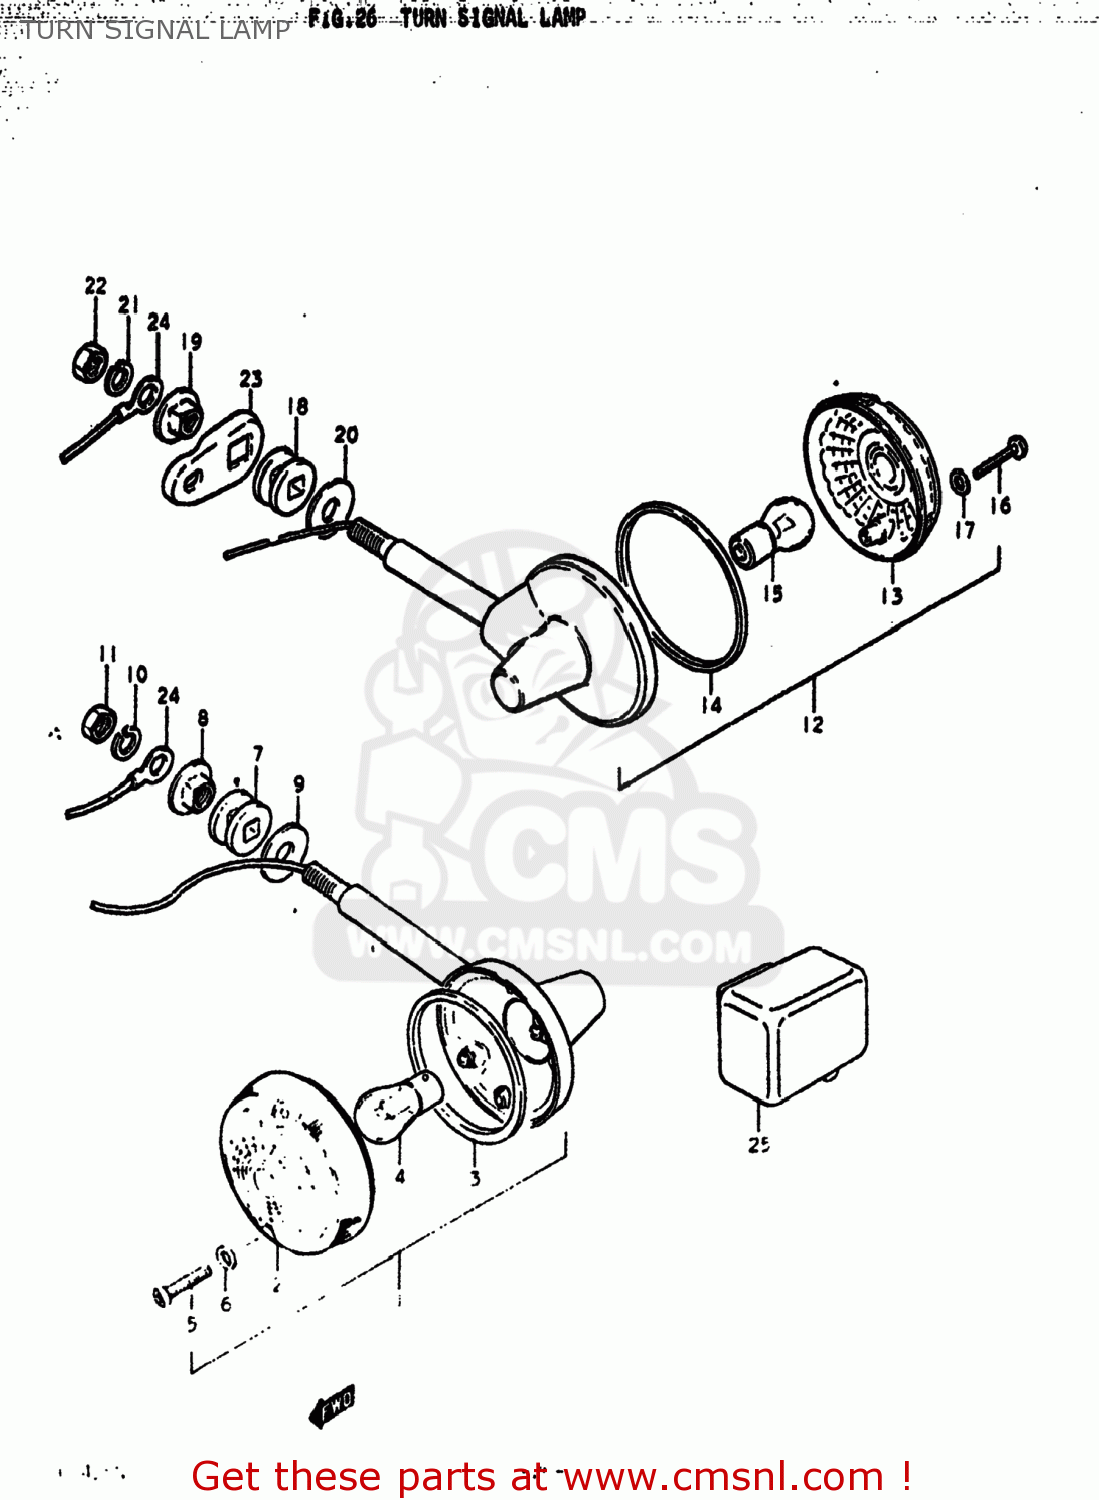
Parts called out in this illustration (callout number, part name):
1	LAMP ASSEMBLY,FRONT TURN SIGNAL
2	LENS
3	GASKET (NAS)
4	BULB(12V23W,STANLEY,A4577A)
5	SCREW
6	GASKET (NAS)
7	CUSHION
8	SPACER,RR TURNSIGNAL LAMP
9	WASHER
10	LOCK WASHER
11	NUT
12	LAMP ASSEMBLY,REAR TURN SIGNAL
13	LENS
14	GASKET (NAS)
15	BULB(12V23W,STANLEY,A4577A)
16	SCREW
17	GASKET (NAS)
18	CUSHION
19	SPACER,RR TURNSIGNAL LAMP
20	WASHER
21	LOCK WASHER
22	NUT
23	BRACKET,TURN SIGNAL
24	LEAD WIRE,EARTH
25	RELAY,TURN SIGNAL
